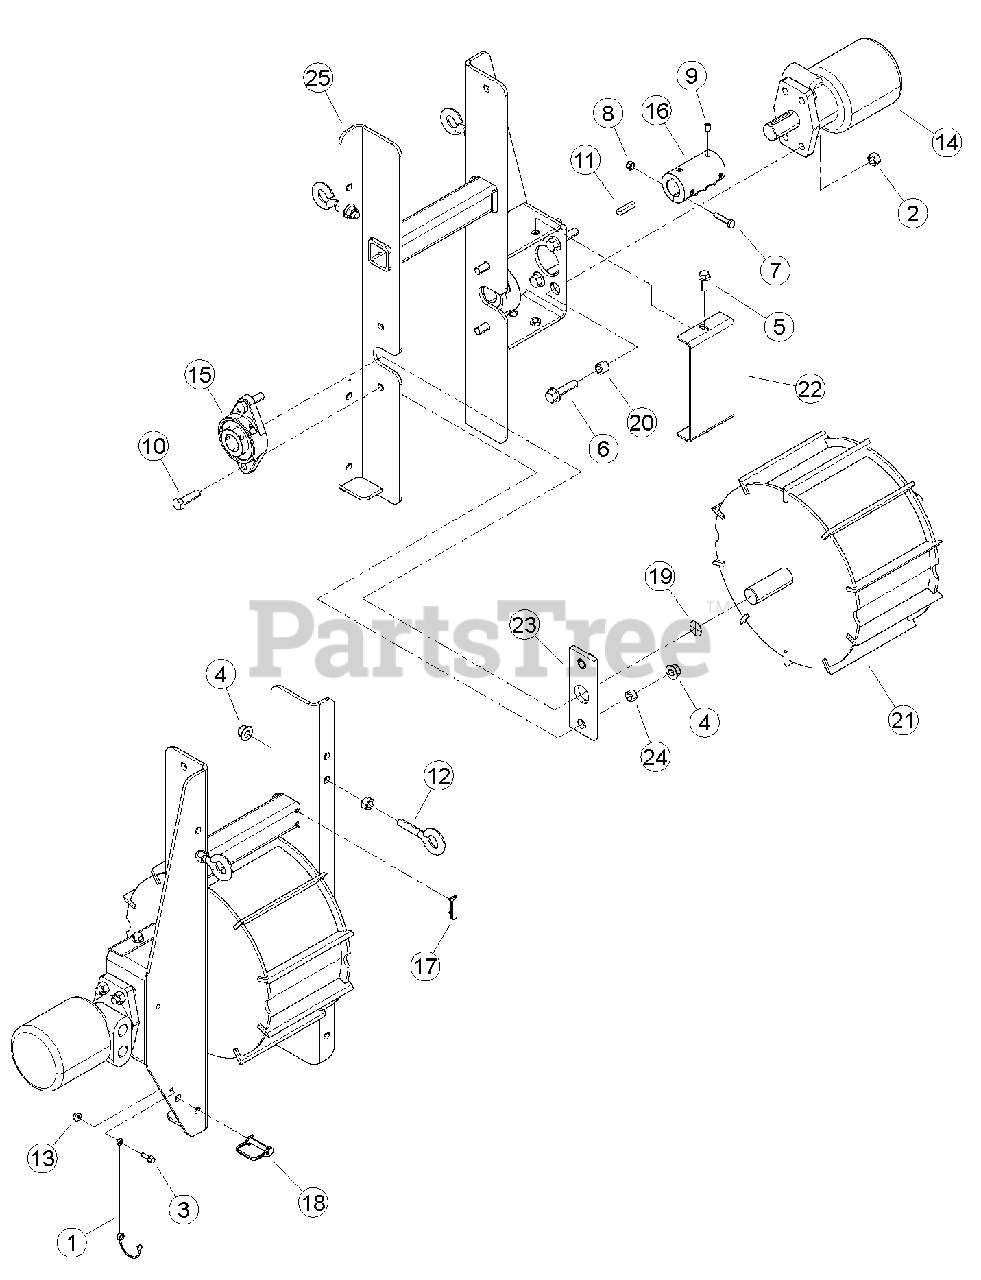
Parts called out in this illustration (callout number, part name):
1	LANYARD, NYLON
2	NUT, 1/2-13 GR5 CENTERLOCK GRB
3	BOLT, 1/4-20 X 3/4 HWH GR5 CZP
4	NUT, 1/2-13 NYLOCK FLANGE
5	BOLT, 3/8 X 1 FLANGE NC
6	BOLT, 1/2-13 X 2 HWH GR5 CZP
7	BOLT, 5/16 X 1-1/2 GR5 HEX CPS ZP
8	NUT, 5/16-18 NE NYLOCK
9	SET SCREW, 3/8 X 1/2 CUP PT SKT
10	BOLT, 1/2-13 X 1-3/4 GR5 HCPS
11	KEY, 5/16 X 1-1/2 SQUARE
12	EYEBOLT, 1/2-13 X 2
13	NUT, 1/4-20 NYLOCK FLANGE
14	MOTOR, 45 CU IN HYDRAULIC
15	BEARING, 1-1/4" DIA 2 BOLT FLANGE
16	COUPLER, 1-1/4 SHAFT
17	WEAR PAD, STD. SPRING HD FRONT
18	PIN, 3/8 X 1-1/2 LYNCH
19	DECAL, ROTATING SHAFT
20	SPACER, 0.75 X 0.620
21	WELDMENT, TOP GRAB ROLLER
22	SHIELD, COUPLER
23	BEARING, SLIDE
24	SPACER, .75 OD X .5 ID X .37
25	WELDMENT, ROLLER SLIDE
